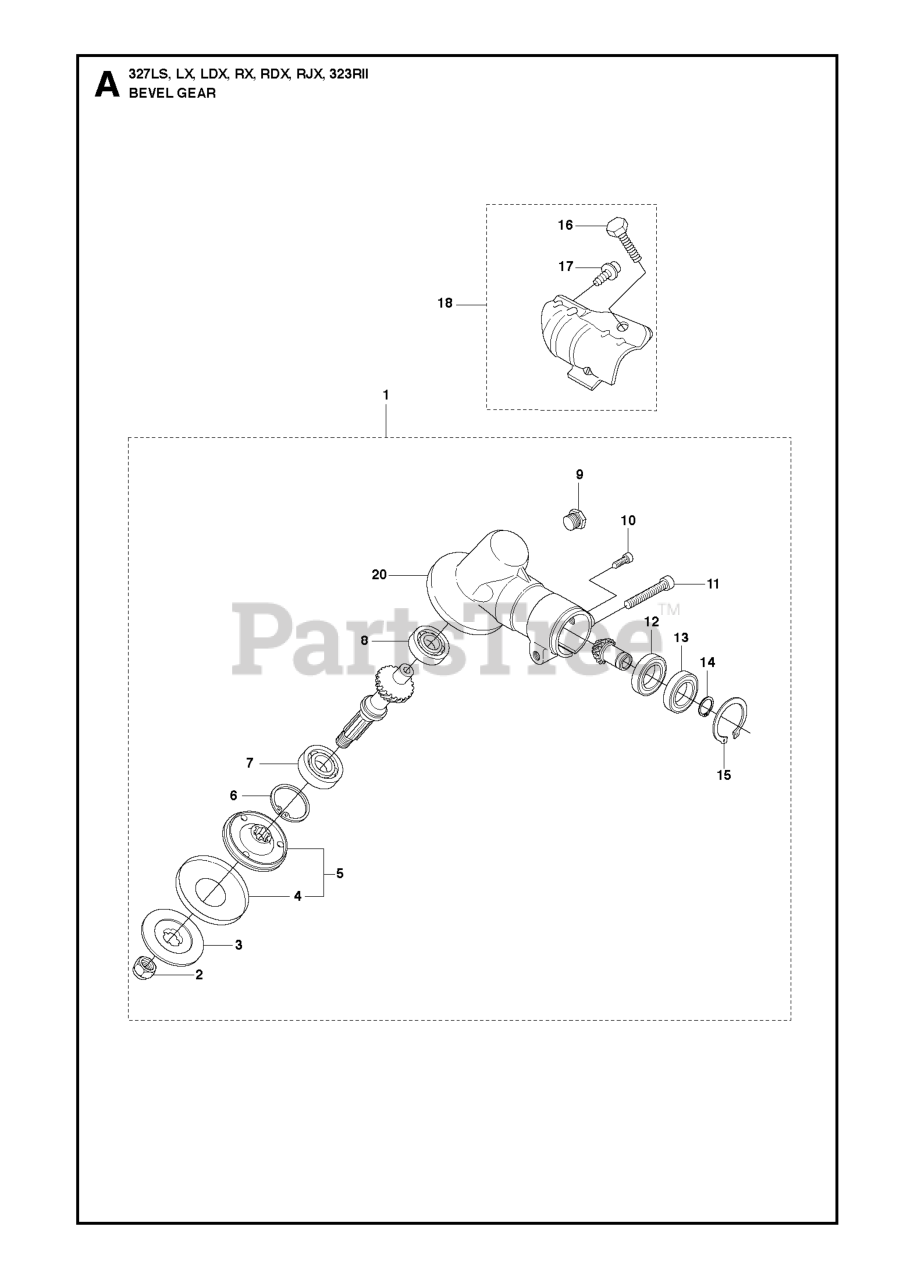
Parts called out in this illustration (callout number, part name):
1	GEAR HEAD
2	GEARHEAD NUT - BRUSHCUTTER
3	SUPPORT FLANGE
4	WASHER
5	DRIVE DISC
6	RETAINING RING SGH 28
7	BEARING
8	BALL BEARING 8X22X7/608Z
12	BALL BEARING 24X9X1/609ZR
14	RETAINING RING
15	RETAINING RING
16	SCREW M6S 6X20
18	CLAMP
20	GEAR HOUSING
